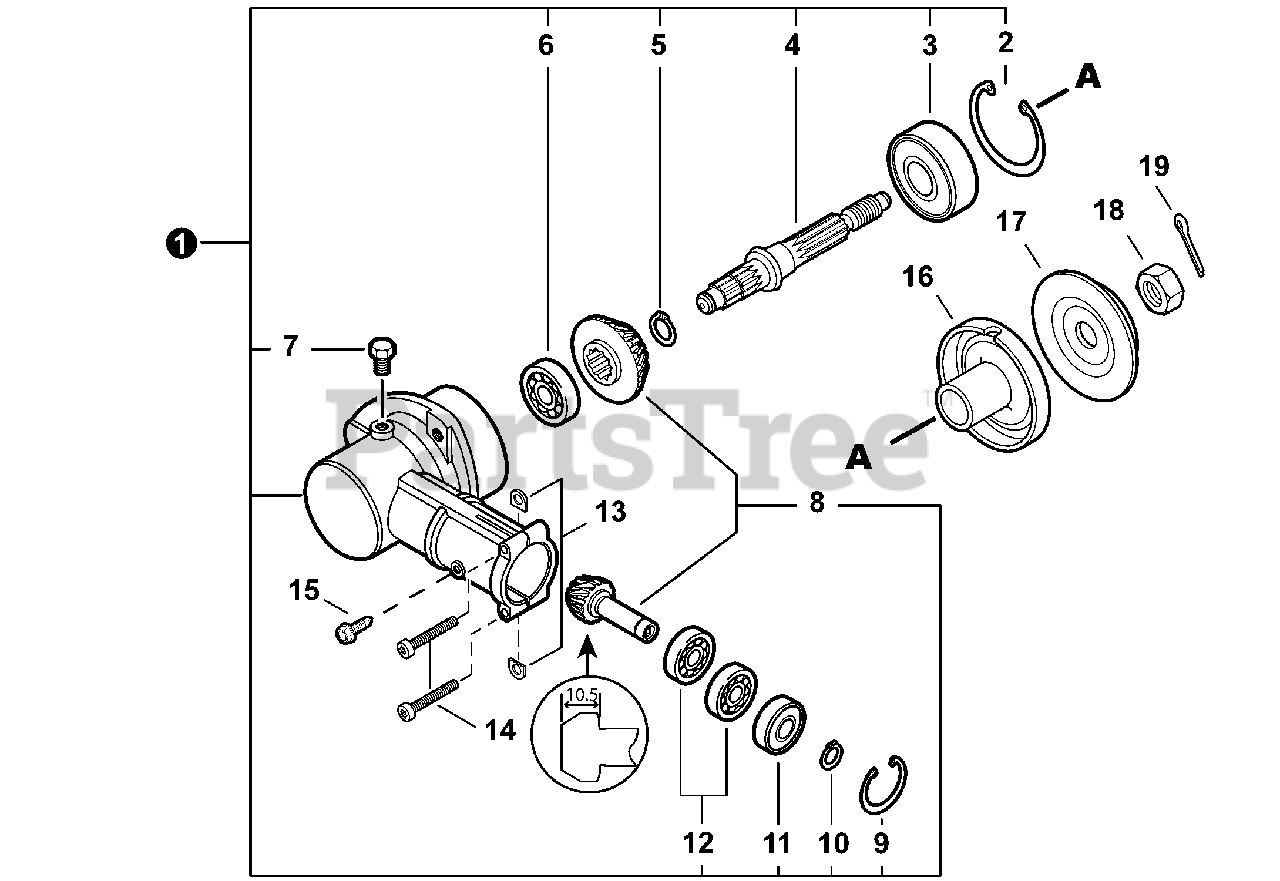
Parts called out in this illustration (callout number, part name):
1	GEAR CASE ASSY
2	RING, SNAP Ø42
3	BEARING, BALL 6302
4	SHAFT, GEAR
5	RING, SNAP Ø12
6	BEARING, BALL 629
7	BOLT M8×8
8	GEAR SET
9	RING, SNAP Ø22
10	RING, SNAP Ø10
11	BEARING, BALL 6900Z
12	BEARING, BALL 6900
14	BOLT, TORX 5×25
15	BOLT, 5 SELF DRILLING
16	PLATE, ADAPTOR - UPPER
17	PLATE, ADAPTOR - LOWER
18	NUT 10×1.25 LH
19	PIN, COTTER 2×22
